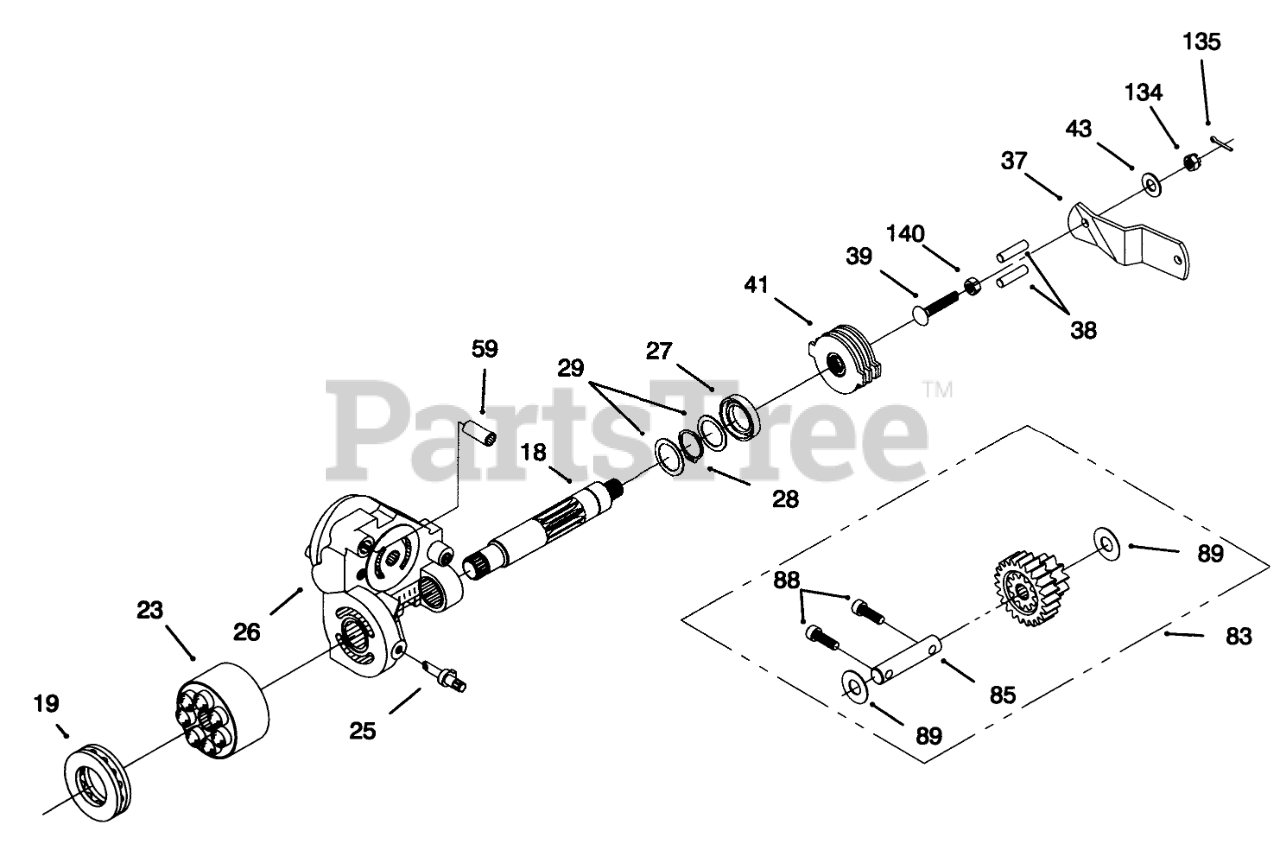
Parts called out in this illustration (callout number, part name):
15	SEAL-LIP
18	SHAFT - MOTOR
19	BEARING - THRUST
23	CYLINDER BLOCK ASM
24	SEAL-LIP
25	ACTUATOR-BYPASS
26	ASM - CENTERSECTION
27	SEAL - LIP
28	RING - RETAINING
29	WASHER
37	Lever-Brake
38	PIN - ACTUATING
39	BOLT 5/16-18 X 1-3/4
41	KIT-BRAKE ROTOR/STATOR
43	WASHER-PIVOT
83	ASM-JACKSHAFT/PINION GEAR
85	JACKSHAFT
88	CAPSCREW
89	WASHER
134	NUT-CASTLE
135	PIN-COTTER
140	NUT-LOCK, NI
